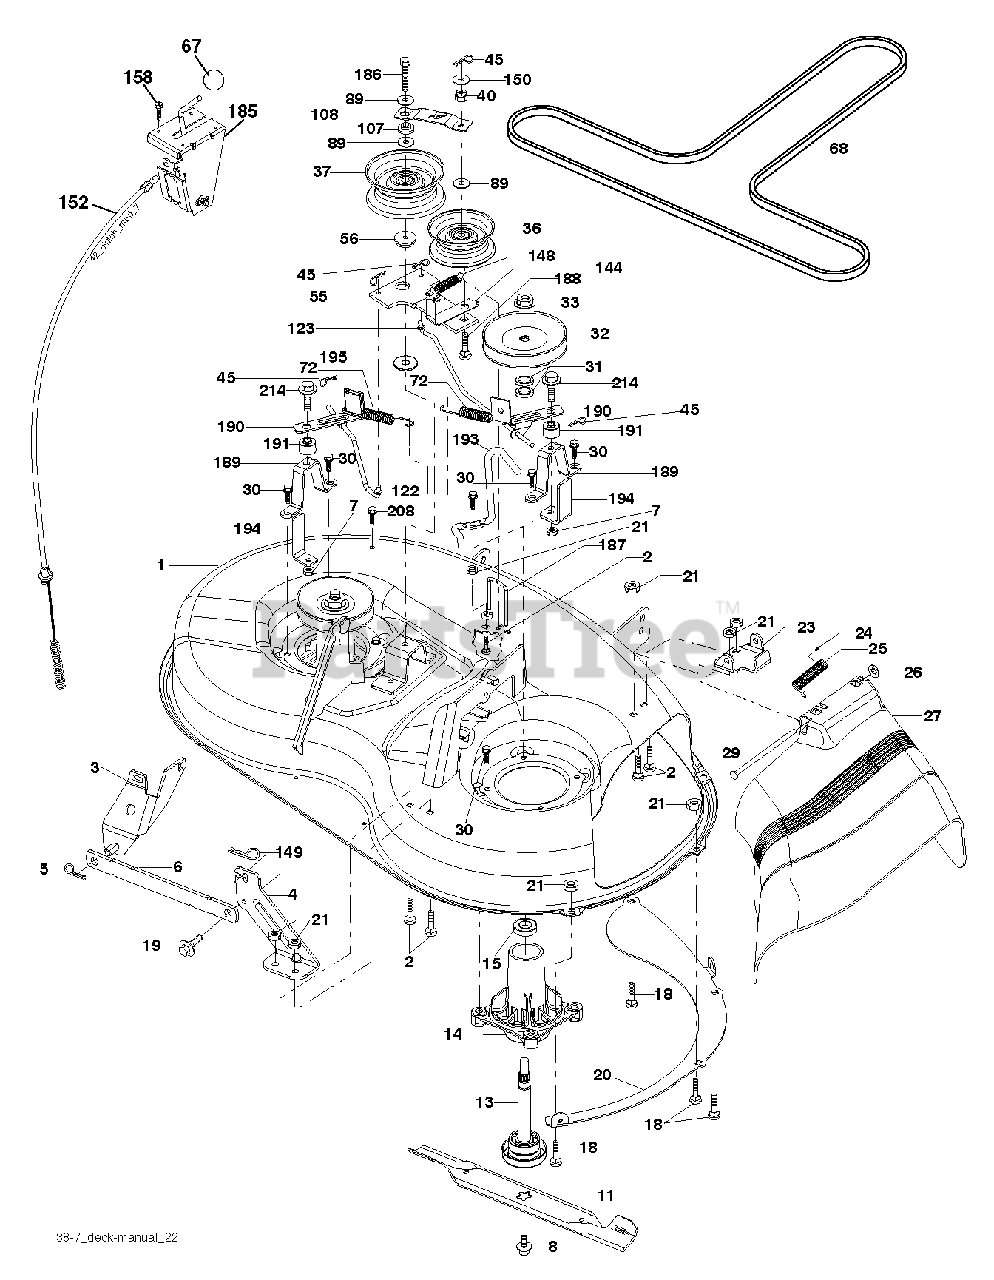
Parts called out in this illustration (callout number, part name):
1	DECK.WELDMENT.38"2005
2	BOLT
3	BRKT ASM SWAY BAR
4	BRACKET DECK SWAY BAR 38"/42""
5	RETAINER-SPRNG RB
6	BAR SWAY DECK
7	NUT.71038.31-18.HEX.NYLOCK
8	BOLT.WASHER.ASM.7/16-2
11	BLADE 38" PREMIUM
13	SHAFT.ASM.MDRL.N/GREASE.38
14	HOUSING.MANDREL.4PT.
18	BOLT
19	BOLT SHD 5/16-18
20	BAFFLE.VORTEX.FRONT.38"
21	LOCKNUT
23	BRKT.DEFLECTOR.38"2005+
24	CAP-SLEEVE LT
25	SPRING.TORSION.DEFLECT
26	NUT PUSH M
27	SHIELD, DEFLECTOR
29	ROD.HINGE
30	SCREW, WASHER HEAD
31	WASHER.SPACER.MANDREL
32	PULLEY MANDREL
33	NUT.FLANGE.LOCK.TOP
36	FLAT IDLER PULLEY
37	PULLEY.IDLER.FLAT.UNPLATED
40	NUT LOCK FLG 3/8-16 UNC
55	IDLER ARM
56	SPACER.RETAINER.MOWER
67	KNOB T (3/8 HOLE)
68	V-BELT.MOWER.38"2005+
72	SPRING.BRAKE.RETURN.38"
107	SPACER.IDLER.ARM
108	STIFFENER.IDLER.ARM
122	LINK.BRAKE.38"LEFT.2007
123	LINK.BRAKE.38"RIGHT
144	KEEPER BELT
148	IDLER RETURN SPRING
149	SPRING.RETAINER.YELLOW.ZINC
150	WASHER LT
152	CABLE.CLUTCH.38".SERVICE
158	SCREW
185	HEAD ASM. CABLE CLUTCH
186	SCREW.HXWSH.3/8
187	KEEPER BELT
191	BRAKE.SPACER.38".DECK
193	KEEPER BELT RH MANDREL
195	WASHER 12/32X2X10GA
208	SCREW 3/8-16X1/2
214	BOLT/WASHER ASM 5/16-18
